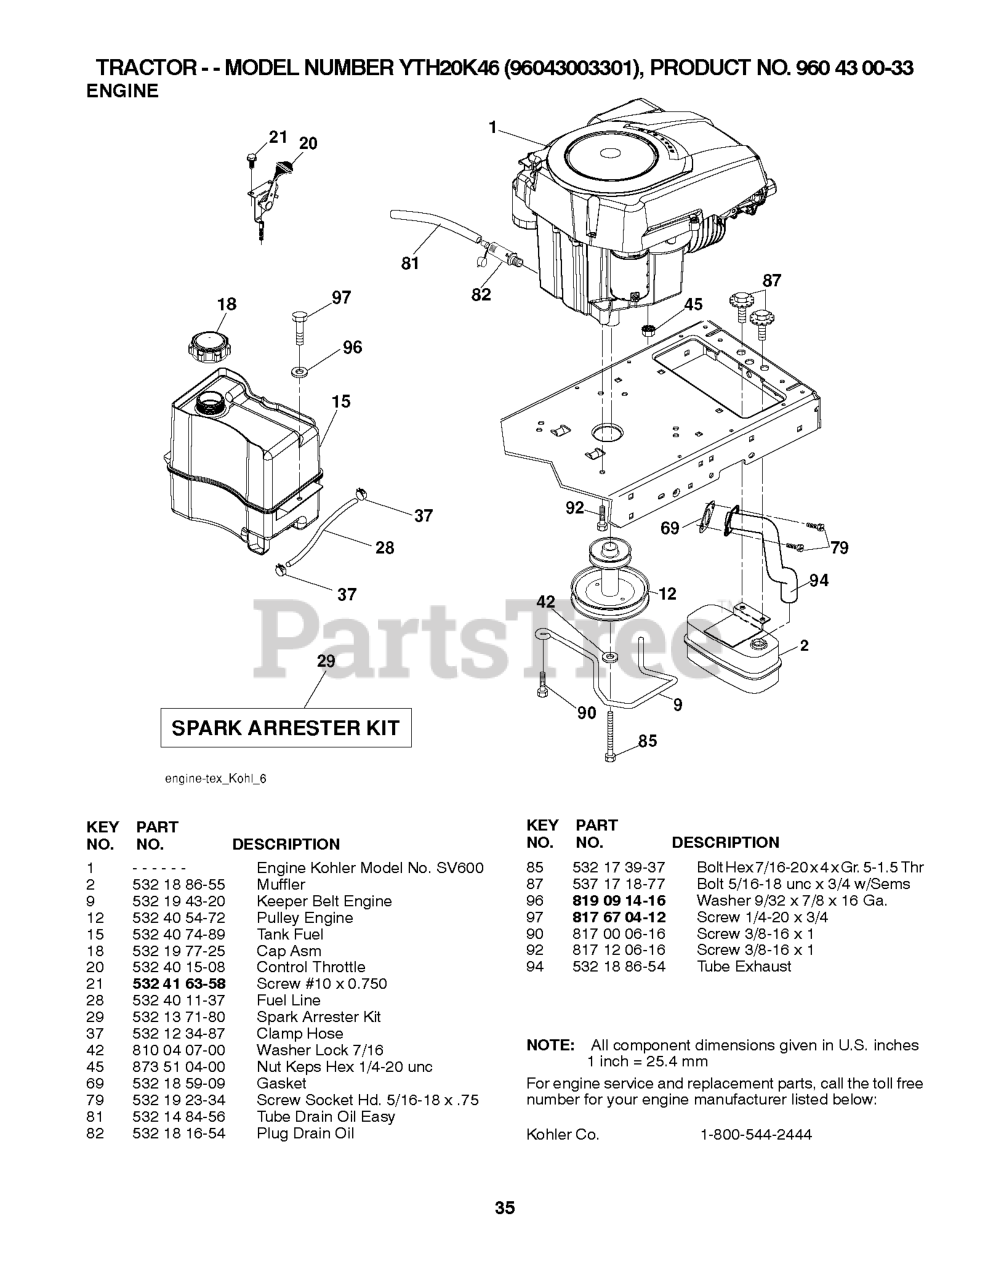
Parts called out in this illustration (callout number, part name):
2	MUFFLER.SINGLE.CYL.KOHL/B&S
9	KEEPER.BELT.ENGINE.4.2
12	RP_PULLEY ENGINE
15	TANK.ASM.FUEL.FR.2.5GA.
18	FUEL CAP
20	CONTROL.TH/CK.COBRA.KO
21	SCREW.#10 X 0.750.BOS
28	LINE.FUEL.20"FRONT.EMI
29	KIT.SPARK ARRESTOR 794945 B&S
37	HOSE CLAMP
42	LOCKWASHER
45	NUT
69	GASKET.EXHAUST.KOHLER
79	SCREW.SOCKET HD.5/16-1
81	TUBE, DRAIN OIL ASM.
82	PLUG DRAIN OIL EASY
85	BOLT HEX 7/16-20X4-1/4"
87	BOLT 5/1618UNC X 3/4 W/ SEMS
90	SCREW 3/8-16X1
92	SCREW 3/8-16X1
94	RP.TUBE.EXHAUST.KOHL.COURAGE
97	SCREW HEXWSHR 1/4-20X3/4
